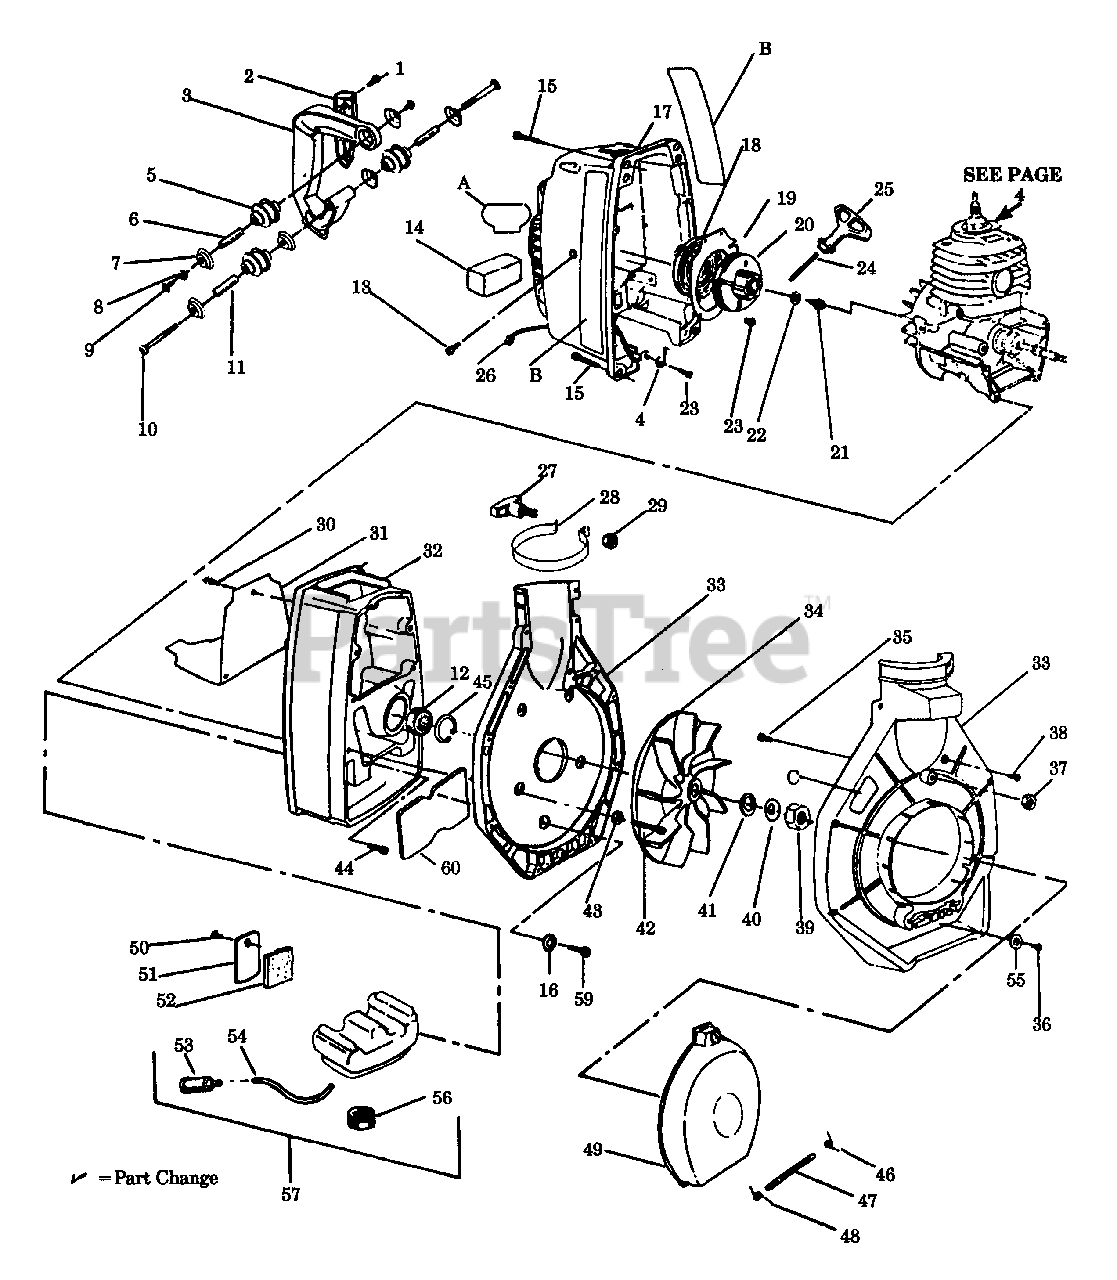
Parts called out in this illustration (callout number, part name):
2	Handle Cover
3	Handle Ass'y.
4	Static Ground Wire
5	Handle Isolator
6	Isolator Spacer (Front)
7	Isolator Cup
11	Isolator Spacer (Rear)
12	Ball Bearing (Shroud)
14	Air Filter
17	Fan Housing
18	Starter Pulley Spring
19	Air Baffle
20	Pulley Replacement Kit
25	Starter Rope Handle
26	Ground Wire
27	"T" Handle Kit
28	Blower Tube Clamp
31	Heat Deflector
32	Shroud
33	Blower Hsg. Kit
36	Screw
38	Screw
41	Washer
43	Washer
45	Shroud Bearing Retainer
46	Spring-Tension (Right)
48	Spring-Tension (Left)
49	Inlet Door Ass'y.
51	Fuel Tank Retainer
52	Fuel Tank Cushion
53	Fuel Pick-Up Ass'y
56	Fuel Cap Ass'y.
57	Fuel Tank Ass'y.
60	Fuel Tank Shield
A	Instruction Decal
B	Fan Housing Decal (Left & Right) - Model 22HB
B	Fan Housing Decal (Left & Right) - Model 28HBV
C	Blower/Vac Warning Decal
